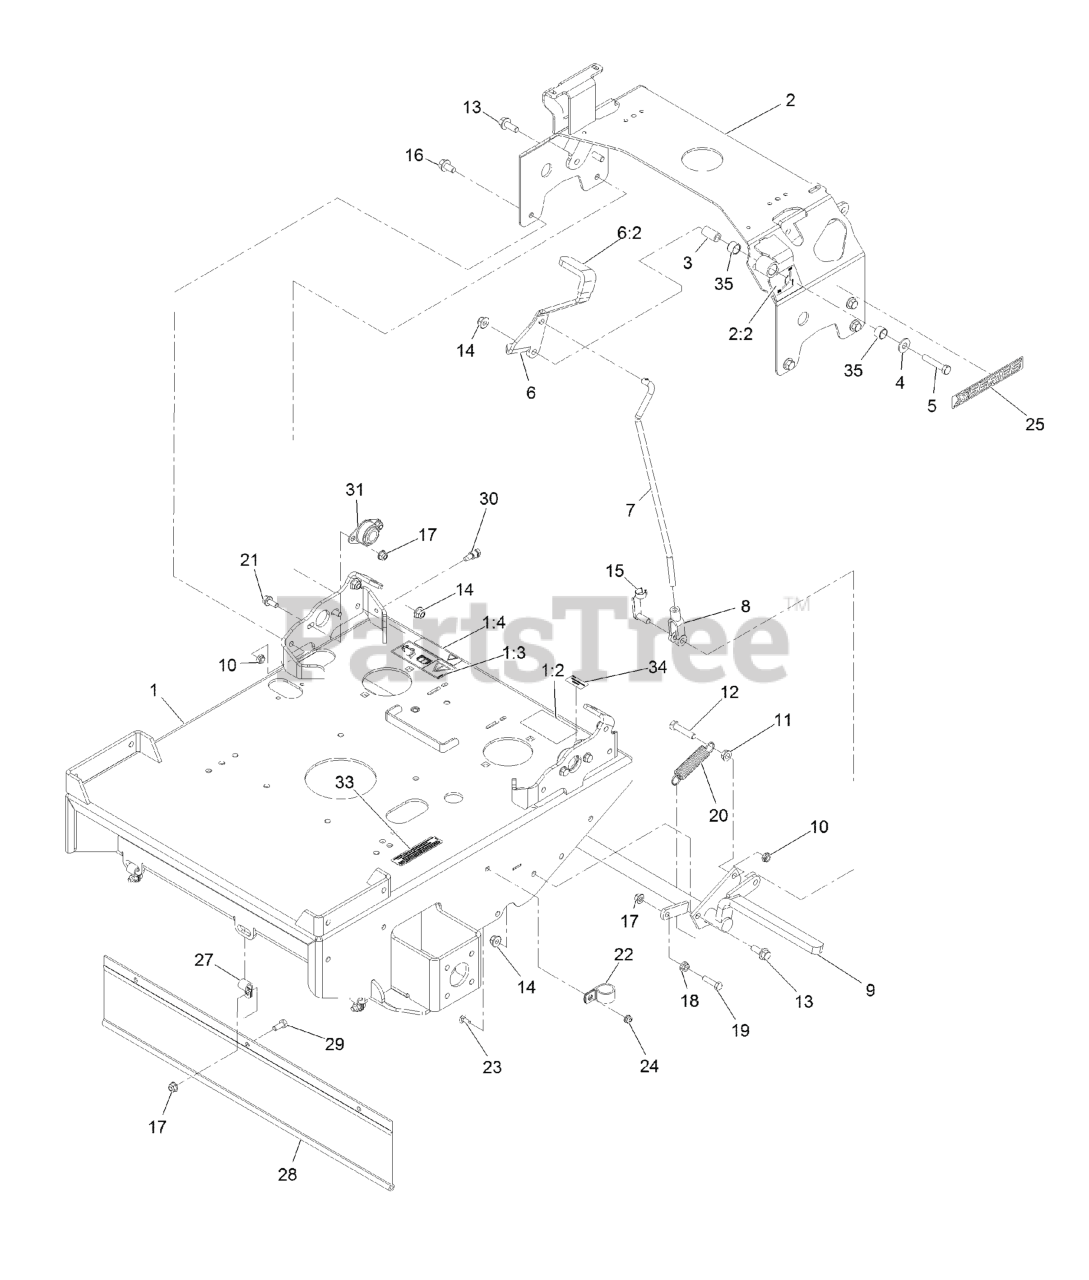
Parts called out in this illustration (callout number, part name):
1	ASM, ENGINE DECK W/ DECAL
1:2	DECAL-WARNING
1:3	DECAL-WARNING, SULKY
1:4	DECAL-DRIVE RELEASE
2	ASM, TANK SUPPORT W/ DECA
2:2	DECAL-PARK BRAKE, CE
3	BUSHING-PIVOT
4	WASHER-FLAT
5	SCREW-HH
6	ASM, BRAKE LEVER W/ GRIP
6:2	GRIP-LEVER
7	LINKAGE-BRAKE
8	YOKE-LINKAGE, BRAKE
9	WLD,BRAKE TTX
11	NUT-HHF, WHIZ
12	SCREW-HH
13	SCREW-HHF 3/8-16 X 1
14	NUT-HF, NI
15	PIN-SPRING, CLEVIS
16	SCREW-HHF
17	NUT-HF, NI
19	SCREW-HH
20	SPRING-IDLER
21	SCREW-HHF
22	CLIP-LOOM
23	SCREW-CARR
25	DECAL-X-SERIES
27	CLIP-LOOM
28	SHIELD,DRAG
29	SCREW-HH
30	BOLT-SHOULDER
31	BEARING-FLANGE, SIDE
33	DECAL-ARRESTOR, SPARK
34	Decal-Patent Ttco.Com
35	SLEEVE-BUSHING
